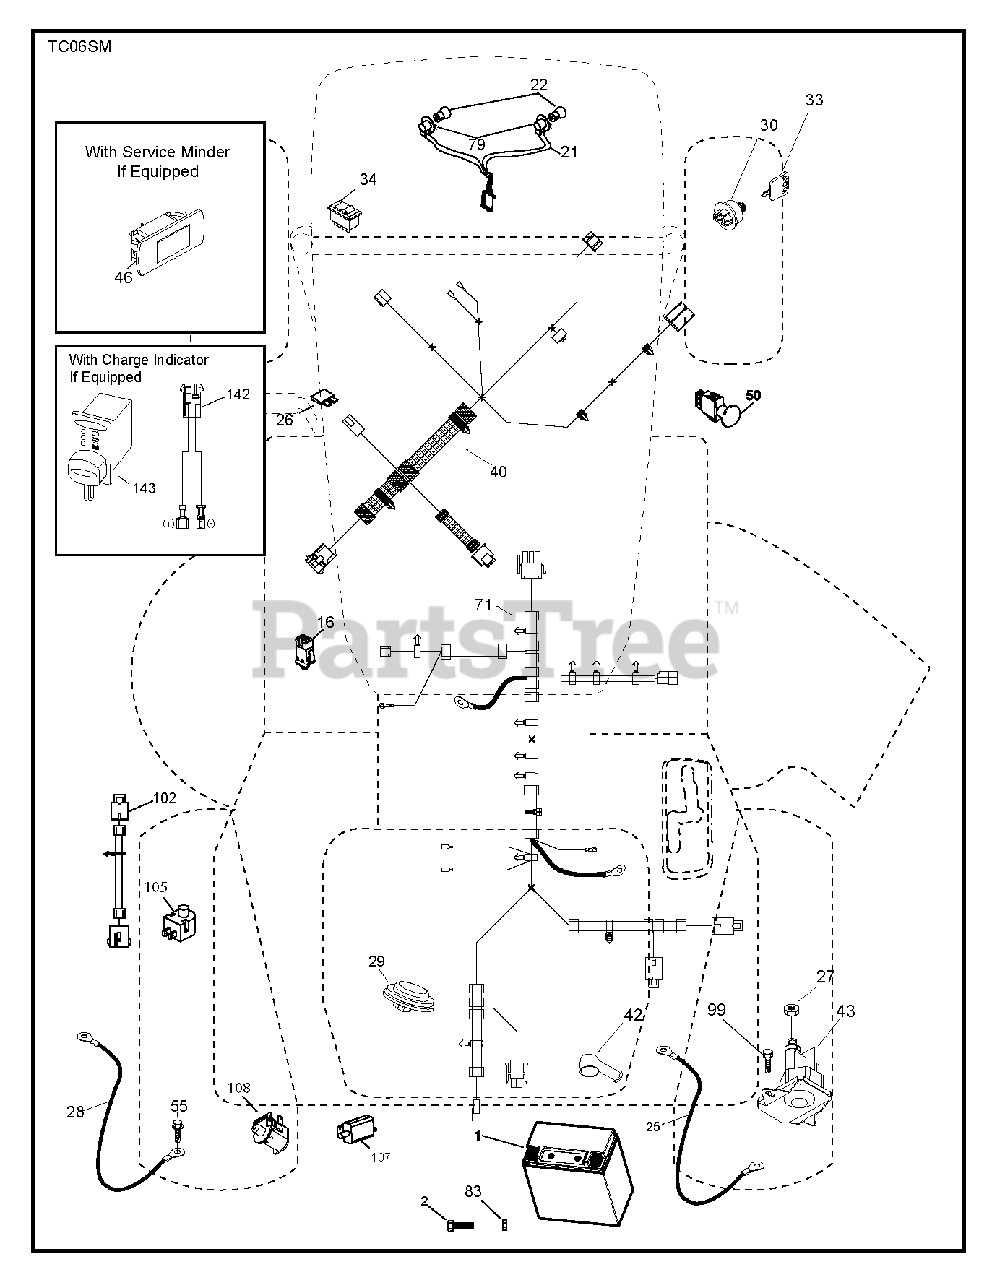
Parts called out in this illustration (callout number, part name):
1	BATTERY BATTERY 14AH 12V LEOC
2	SCREW.HEX.HEAD.CAP.M6 X1.12W
16	SWITCH INTERLOOK PUSH-IN
21	HARNESS.LIGHT W/4152J BULBS
25	CABLE.BATT.8GA.RED9.C
26	FUSE 20AMP
27	NUT
28	CABLE.BATT.BLCK10.SLV
29	SWITCH.SEAT.DELTA.OPC.
30	SWITCH.IGN.DELTA.W.LGH.ROS
33	KEY.CHAIN.BLISTER.PACK.GEN.INT
40	HARNESS.DASH.EL.SRD.CRD.RDY.ST
42	TERMINAL COVER
43	SOLENOID.STARTER.BRASS.PLUNGER
46	GUAGE.SRVCMNDR.HRMTR.
50	SWITCH.PTO.8TERMINAL.STD.BLK
55	SCREW 5/16"
71	HARNESS.CHASS.CRD.TEX.RDY.STRT
79	HARNESS.LIGHT W/4152J BULBS
83	NUT NUT SQUARE
99	SCREW HEXWSHR 1/4-20X3/4
102	HARNESS ASSY
105	REVERSE SWITCH
107	.WITCH.FULL BAGGER.INDICATOR
108	SWITCH.SNAPMOUNT.NC
142	CHARGE.PORT.PIGTAIL HARNESS
143	CHARGE.PORT
